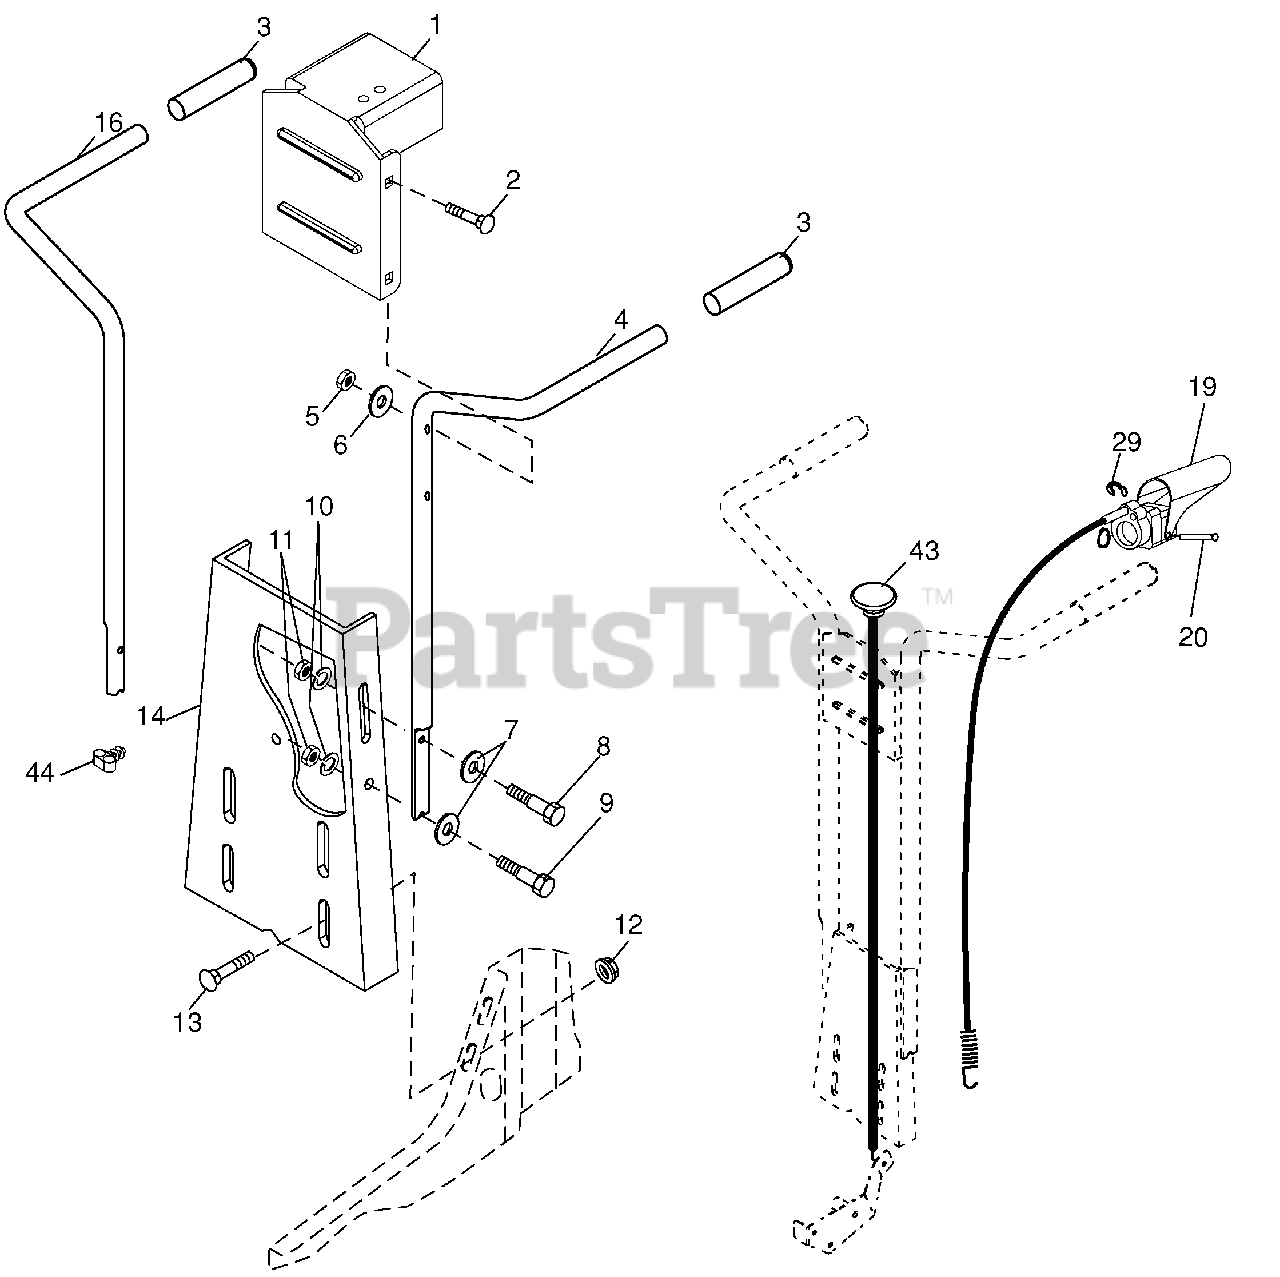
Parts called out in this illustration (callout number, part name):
1	Bracket, Handle
2	Bolt, Carriage 5/16-18 x 1-1/2
3	Grip, Handle
4	Handle, L.H.
5	Nut, Hex, Crownlock 5/16-18
6	Washer 11/32 x 11/16 x 16 Gauge
7	Washer 3/8 x 7/8 x 14 Gauge
8	Bolt, Hex Head 5/16-18 x 1-1/4
9	Bolt, Hex Head 5/16-18 x 1
10	Washer, Lock 5/16
11	Nut, Hex 5/16-18
12	Nut, Hex, Flanged 5/16-18
13	Bolt, Carriage, Gr. 5 5/16-18 x 3/4
14	Panel, Handle
16	Handle, R.H.
19	Tine Control Lever Assembly
20	Pin, Pivot
29	Retaining Ring
43	Cable Assembly, Reverse
44	Clip
